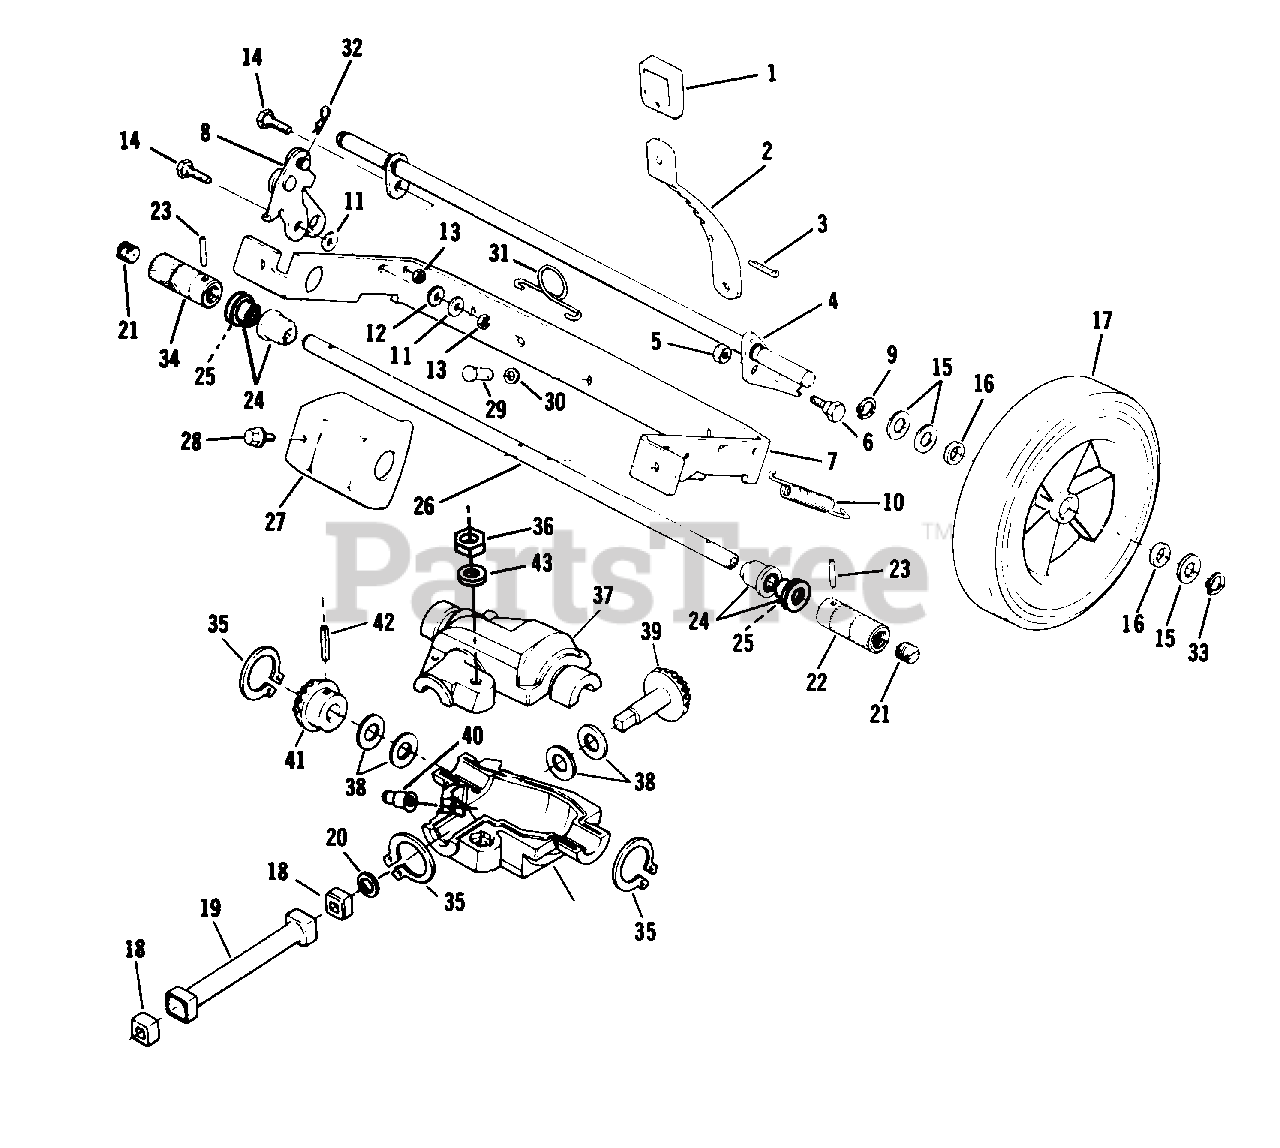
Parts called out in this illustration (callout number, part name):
1	Knob-Rear Height Adj. Lvr.
2	Lever-Rear Height Adj.
3	Cotter Pin
4	Axle Assembly
5	Locknut
6	Bolt-Shoulder
7	Bracket-21" Axle
8	Clutch Assembly
9	Retaining Ring
10	Spring
11	Washer
12	Lockwasher
13	Stopnut
14	Bolt-Shoulder
15	Washer
16	Washer-Felt
17	Wheel-Rear
18	Bushing
19	Tube-Drive
20	"O" Ring-Spacer
21	Plug
22	Drive Roller-L.H.
23	Pin-Spiral
23	Pin-Groove
24	Sleeve and Bearing Assembly
25	P/M Bearing
26	Shaft
27	Guard-Roller
28	Screw
29	Pin-Rr. Hgt. Adj. Lever
30	Spring Washer
31	Spring-Height Adjust
32	Lock Pin
33	Retaining Ring
34	Drive Roller-R.H.
35	Ring-Retaining
36	Locknut
37	Gear Box Assembly
38	Washer
39	Gear-Drive
40	Zerk Fitting
41	Gear Driven
42	Spring Pin
43	Washer
